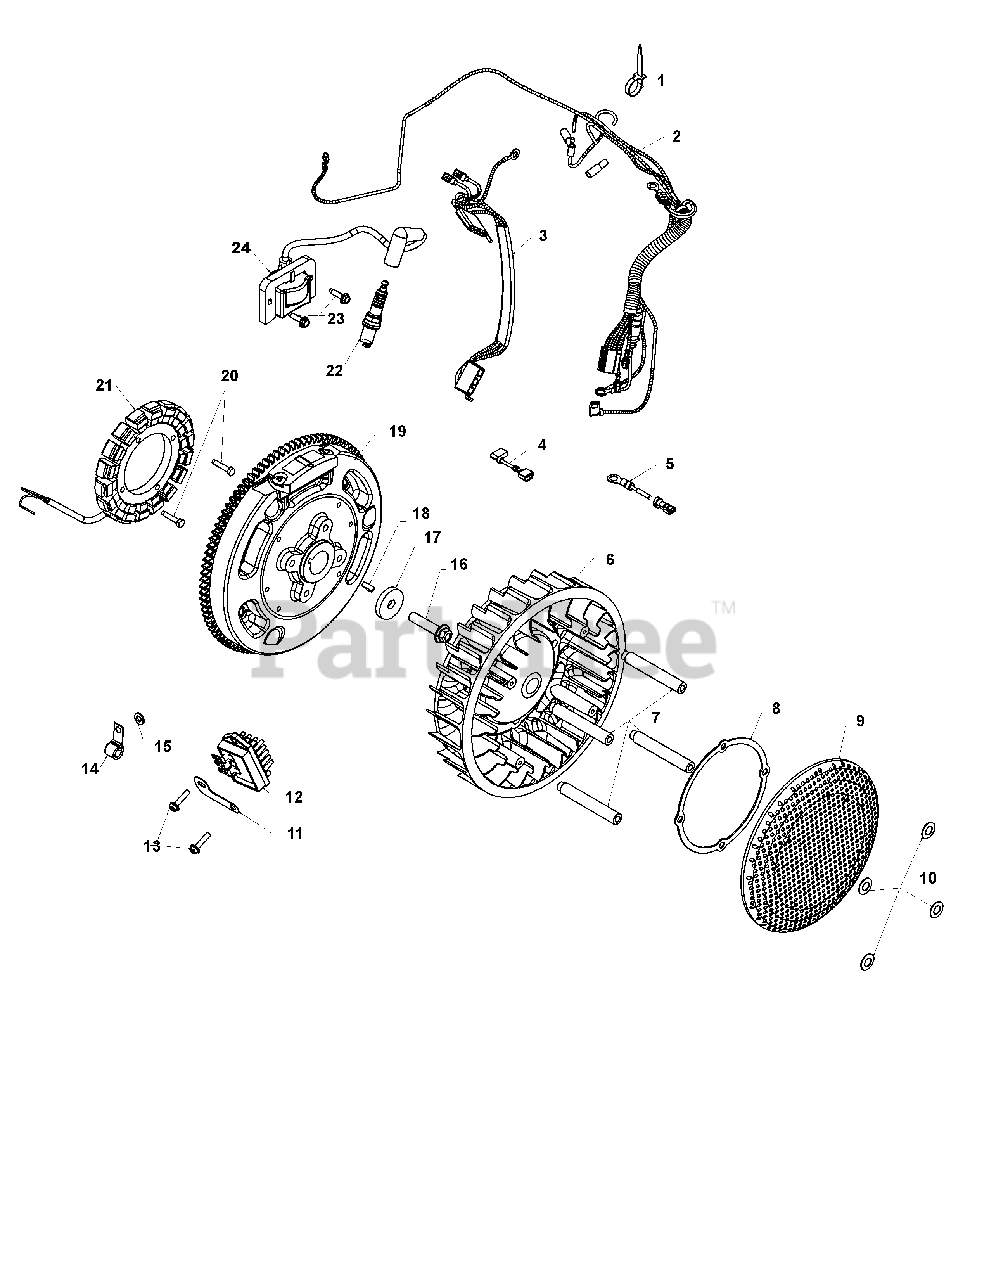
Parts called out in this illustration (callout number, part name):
2	Harness, Wiring Assembly
3	Harness, Dsai Wiring
4	Lead, Oil Sentry
5	Lead, 20/25 Amp B+
8	Ring, Support
9	Screen, Grass
10	Washer, Spring 10 Mm
11	Bracket, Ground Strap
12	Regulator, Rectifier
13	Screw, Hex Flange Hi-Lo
14	Clip, Cable
15	Washer, Flat 1/4'' (O.D. 1/2'')
16	Screw, Flg M10X1.5X45
17	Washer, Flat 13/32''
18	Key, 3/16'' X 5/8''
19	Flywheel Assembly (Lw)
20	Screw, Thd Frm M5X0.8X25
21	Kit, 15 / 20 Amp Stator
22	Plug, Spark (Std)
23	Screw, Flg Thd Frm M5X.8X20
24	Module, Spark Adv (Dsai) Assy
